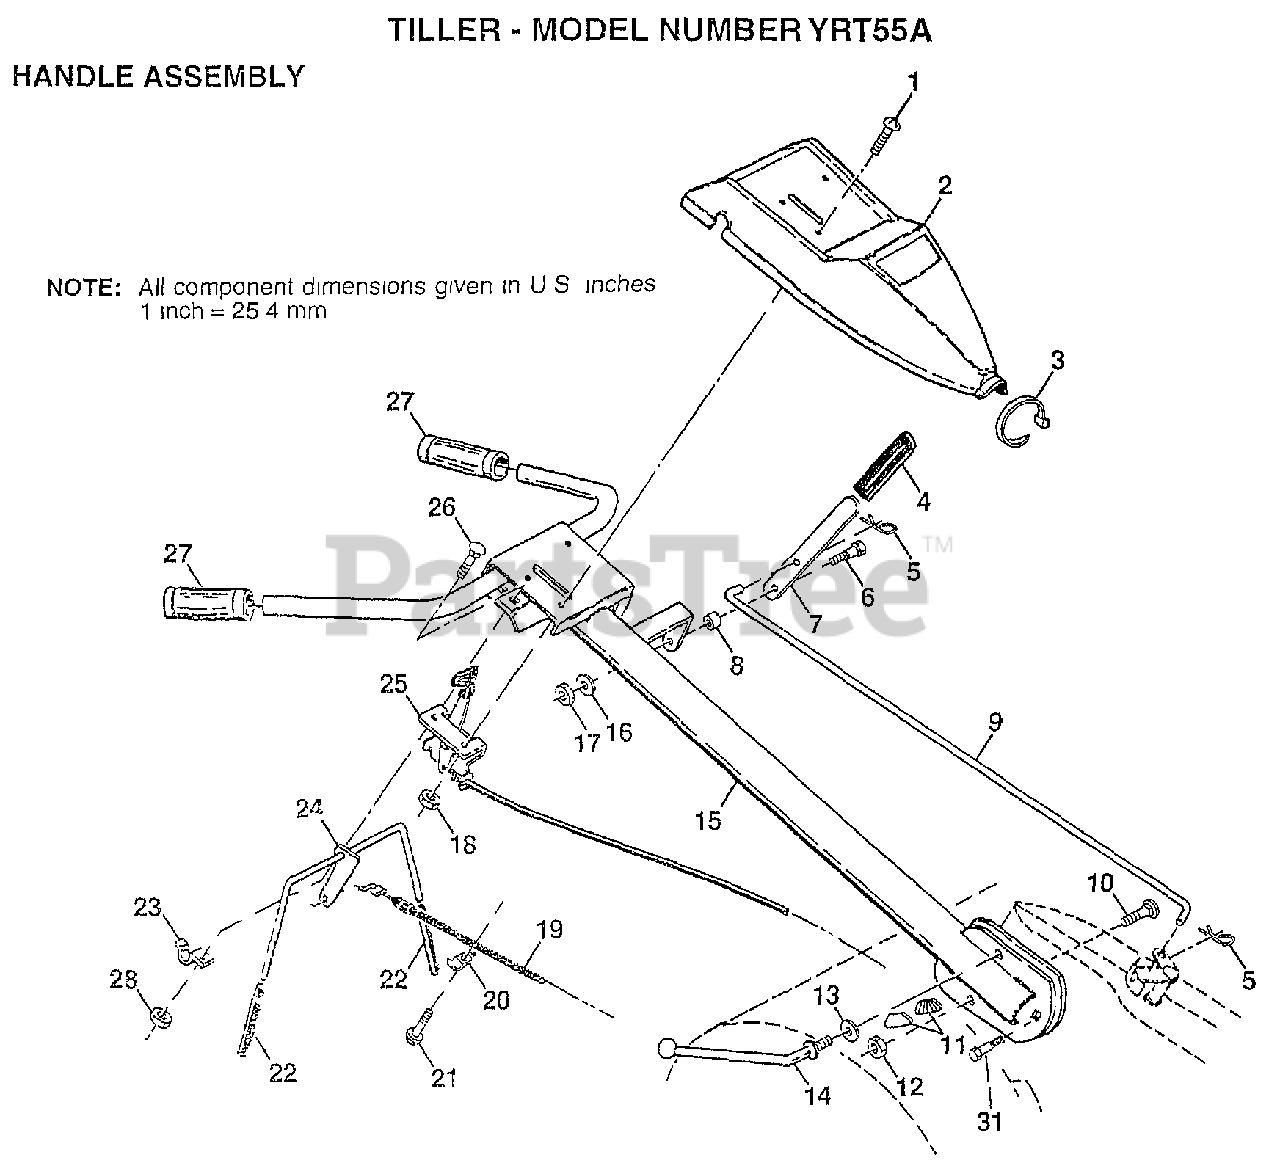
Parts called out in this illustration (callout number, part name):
1	SCREW.PNHD.10-24
2	"PANEL,CONT TI"
3	TIE CABLE CRT
4	GRIP T
5	RETAINER M
6	SHOULDER BOLT ST
7	SHIFT HANDLE CRT
8	GROMMET CRT
9	SHIFT ROD CRT
10	BOLT D
11	LOCK CRT
12	LOCKNUT
13	WASHER CRT
14	LEVER LOCK CRT
16	LOCKWASHER
19	CABLE.CLUTCH.48.Z
20	CONDIUT CLIP T
22	GRIP BAR CRT
24	"ASSY CONTROL, BAR"
25	"CONT,THROTTLE"
26	BOLT
28	NUT
31	BOLT PIVOT
